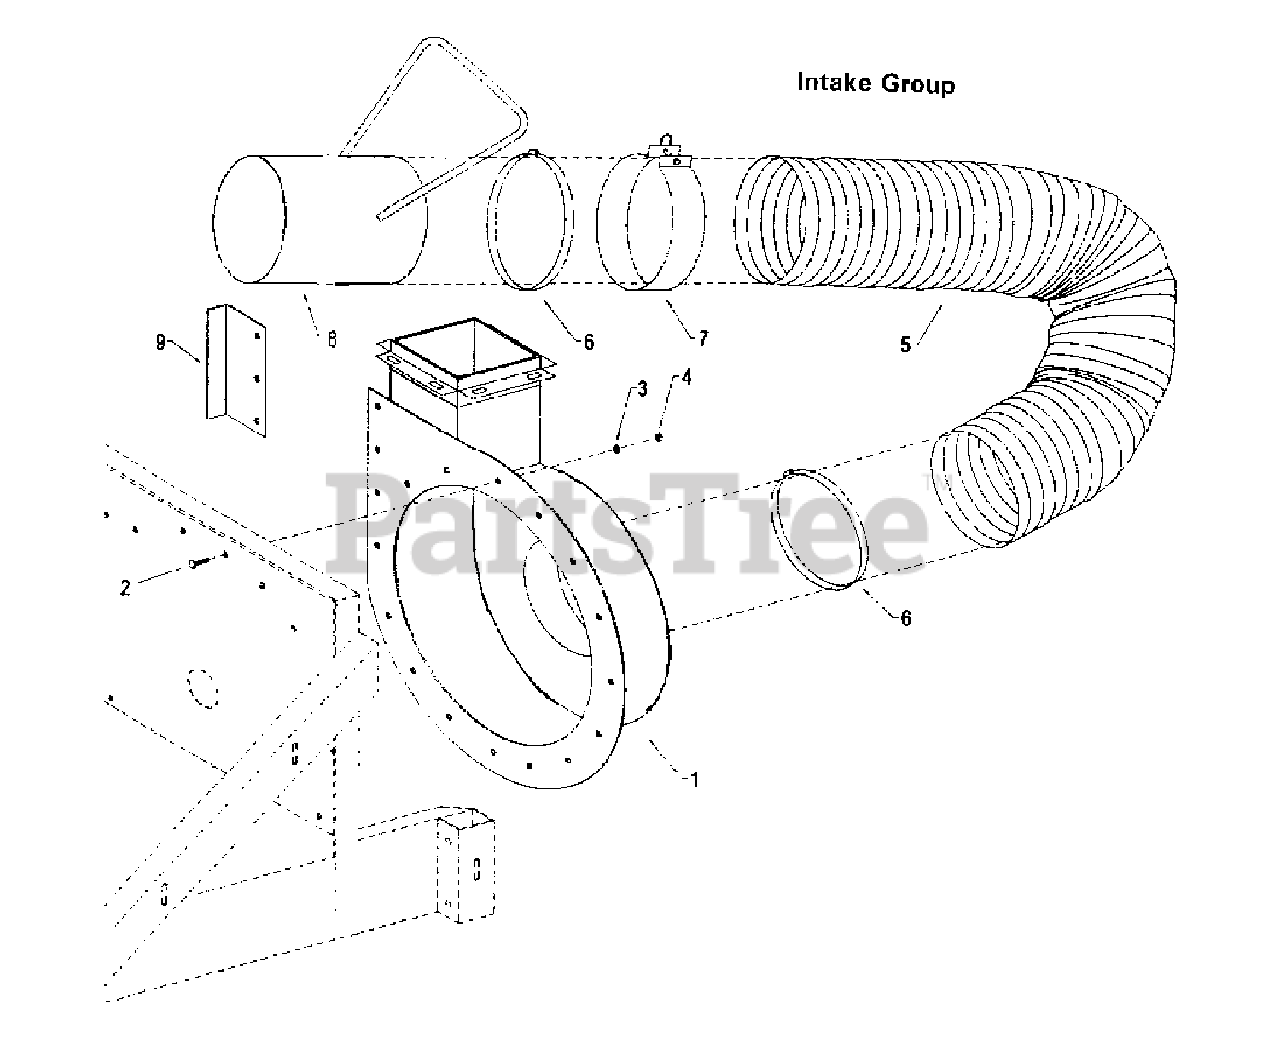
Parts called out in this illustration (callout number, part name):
1	Housing, Impeller - Complete with Liner Kit Below
2	3/8-16 x 1 Hex Bolt
3	3/8 Lock Washer
4	3/8-16 Hex Nut
5	Hose, Intake 12" x 10'
6	Clamp, Hose 12"
6	Clamp, Hose 12" with Safety Swtich Activator Plate
7	Band, Hose Support 12" with Hardware
8	Nozzle, Intake 12" w/Adjustable Handle
9	Plate, Hose Protector
